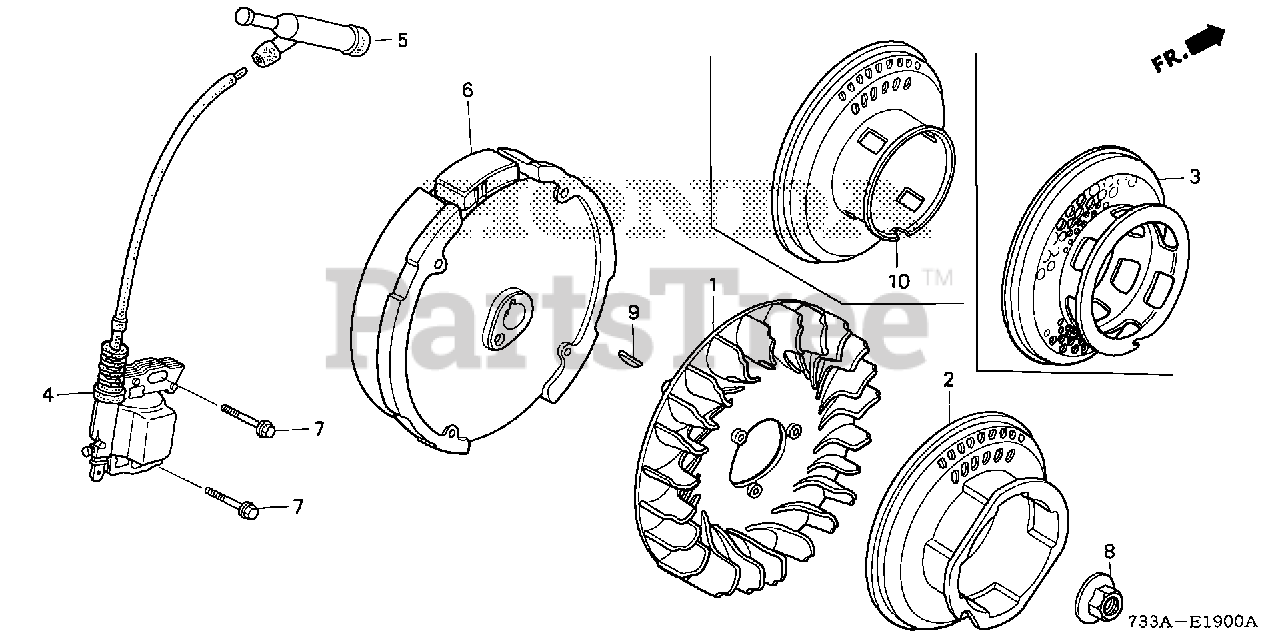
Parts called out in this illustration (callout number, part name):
1	FAN, COOLING
3	PULLEY, STARTER
4	COIL ASSY., IGNITION
5	CAP ASSY., NOISE SUPPRESSOR (NICHIWA Y-EZ RTFM256)
7	BOLT, FLANGE (6X25) (CT200)
8	NUT, SPECIAL (14MM)
9	KEY, SPECIAL WOODRUFF (25X18)
